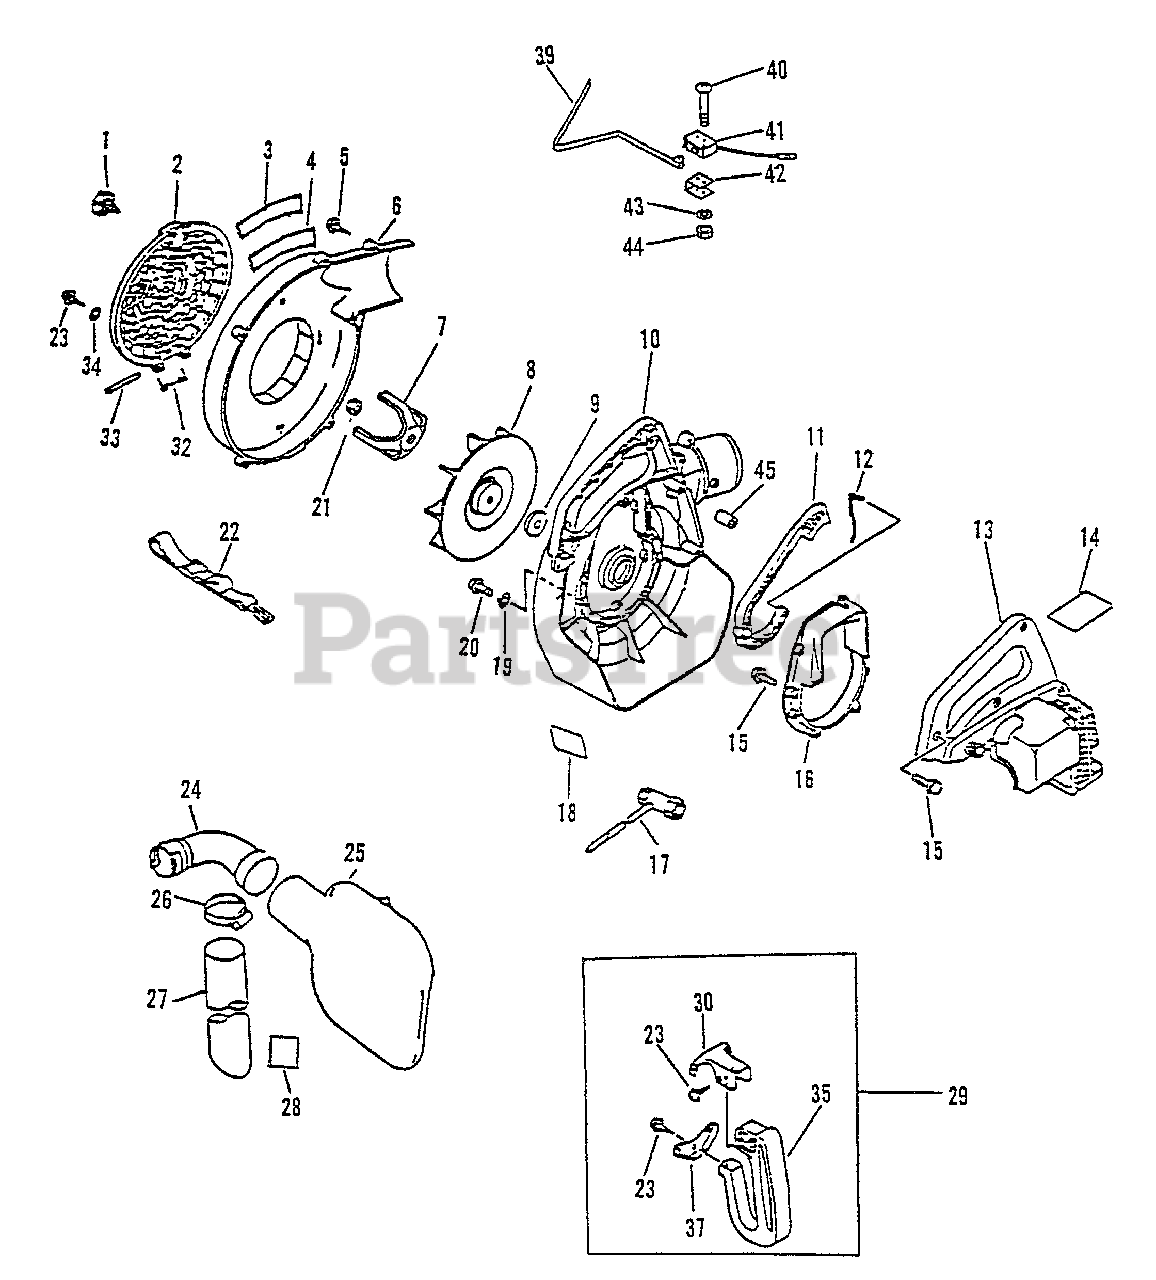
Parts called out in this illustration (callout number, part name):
1	THUMBSCREW
2	SHIELD, DEBRIS
3	LABEL - SAFETY
4	LABEL - MODEL
5	SCREW, TAPPING 5×20
6	COVER, FAN - LEFT
7	BLADE, SHREDDER
8	FAN
10	COVER, FAN - RIGHT
11	TRIGGER, THROTTLE
12	ROD, THROTTLE
13	COVER, ENGINE
14	LABEL - CAUTION -- HOT
15	SCREW 4×18
16	BRACKET, ENGINE
17	T-WRENCH 13×19×180
18	LABEL - CAUTION
20	SCREW 4×22
23	SCREW 5×14
25	BAG, DUST
27	TUBE, VACUUM
28	LABEL - SHRED 'N' VAC
29	HANDLE ASSY, SIDE
30	BRACKET, UPPER HANDLE
32	SPRING, COIL
33	PIN, INTAKE COVER
37	BRACKET, LOWER HANDLE
39	ACTUATOR
40	SCREW
41	IGNITION SWITCH ASSY
43	LOCKWASHER
45	TUBE, RETAINER
